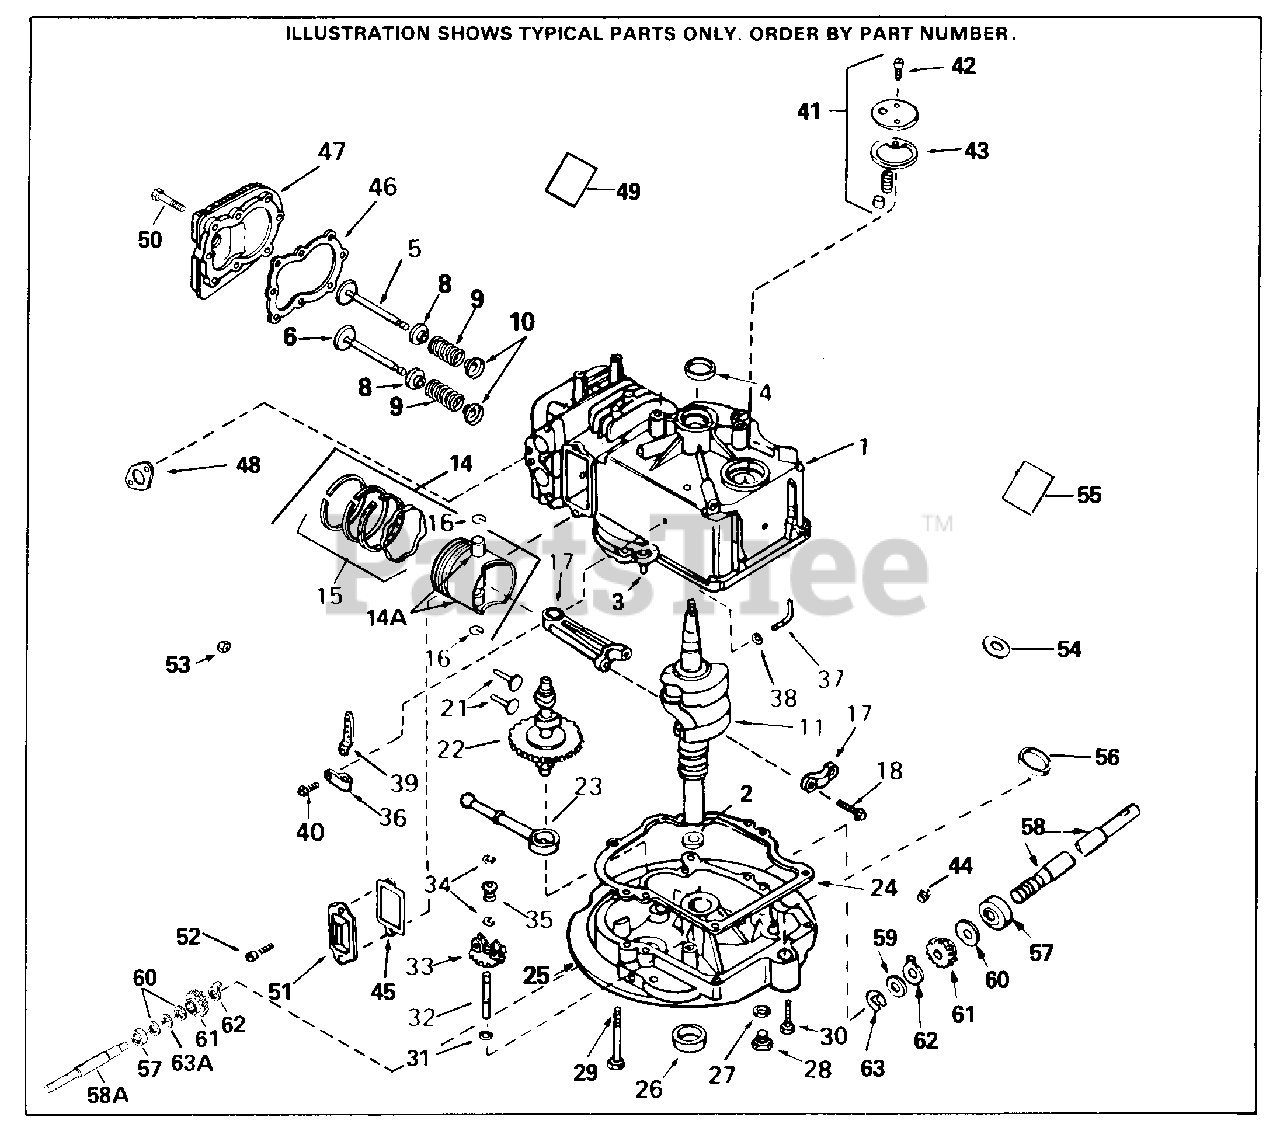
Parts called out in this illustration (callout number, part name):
1	"Cylinder (Incl. 3,4,41,42,43 & 54) 2- 5/8"
3	Dowel Pin
4	Seal, Oil
5	Intake Valve (Std.) (Incl. 151)
5	Exhaust Valve (1/32" OS) (Incl. 151)
6	Exhaust Valve (Std.) (Incl. 151)
6	Exhaust Valve (1/32" OS) (Incl. 151)
8	Upper Valve Spring Cap Early prod. on ly
9	Spring, Valve
10	Cap, Lower valve spring
11	Crankshaft
14	Piston, Pin & Ring Set (Std.) 2-5/8"B ore
14	Piston, Pin & Ring Set (.010" OS)
14	Piston, Pin & Ring Set (.020" OS)
14A	Piston & Pin Ass'y. (Std.) (Incl. 16) (2-5/8")
14A	Piston & Pin Ass'y. (.010" OS) Incl. 16
14A	Piston & Pin Ass'y. (.020" OS) Incl. 16
15	Ring Set (Std.) (2-5/8" Bore)
15	Ring Set (.010" OS)
15	Ring Set (.020" OS)
16	Piston Pin Retaining Ring
17	Rod Assy., Connecting (Incl. 18)
18	Bolt, Connecting rod
21	Valve Lifter
22	Camshaft (MCR)
23	Oil Pump Ass'y.
24	Mounting Flange Gasket
25	Mounting Flange Assy. Incl. 26,27,28, 32,44,56
26	Oil Seal
27	Drain Plug Gasket
28	Plug, Oil drain
29	Screw, 1/4-20 x 1-1/4"
30	Screw, 1/4-20 x 1-1/4"
31	Washer, Flat
32	Shaft, Mechanical governor
33	Gear Assy., Governor (Incl. 31)
34	Retaining Ring
35	Spool, Governor
36	Clamp, Governor lever
37	Rod, Governor (Incl. 38)
38	Flat Washer
39	Lever, Governor
40	Screw, 8-32 x 5/16"
41	Breather Assy. (Incl. 42 & 43)
42	Screw, 10-24 x 9/16"
43	Gasket, Breather
44	Plug, Pipe
45	Valve Cover Gasket
46	Gasket, Cylinder head
48	Gasket, Intake to cylinder
49	Decal, Instruction
51	Cover, Valve spring box
52	Screw, 10-24 x 1/2"
53	Nut, Carburetor bowl
54	Washer, SE brake
